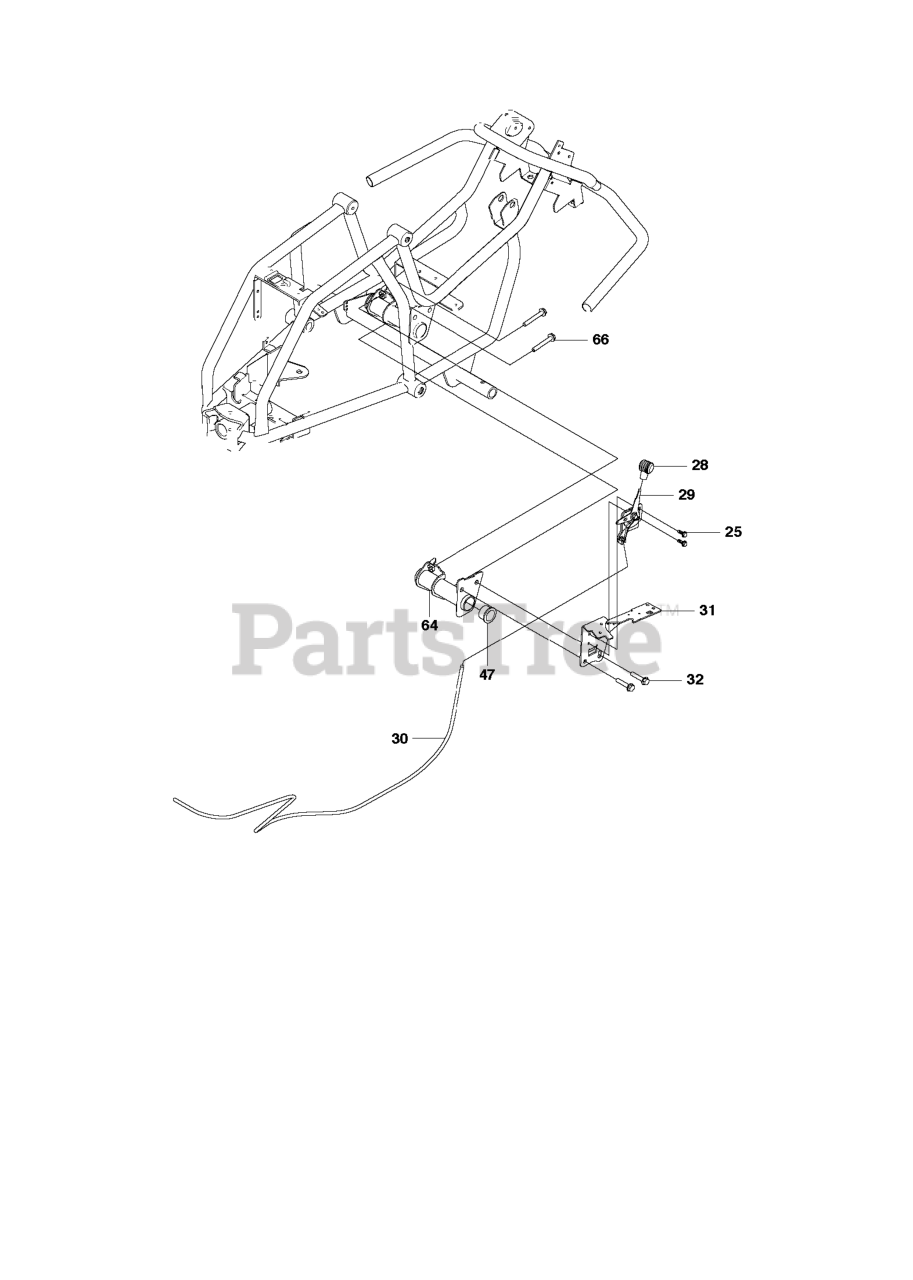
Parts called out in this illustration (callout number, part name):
29	THROTTLE CONTROL
47	ROLLER
66	SCREW
